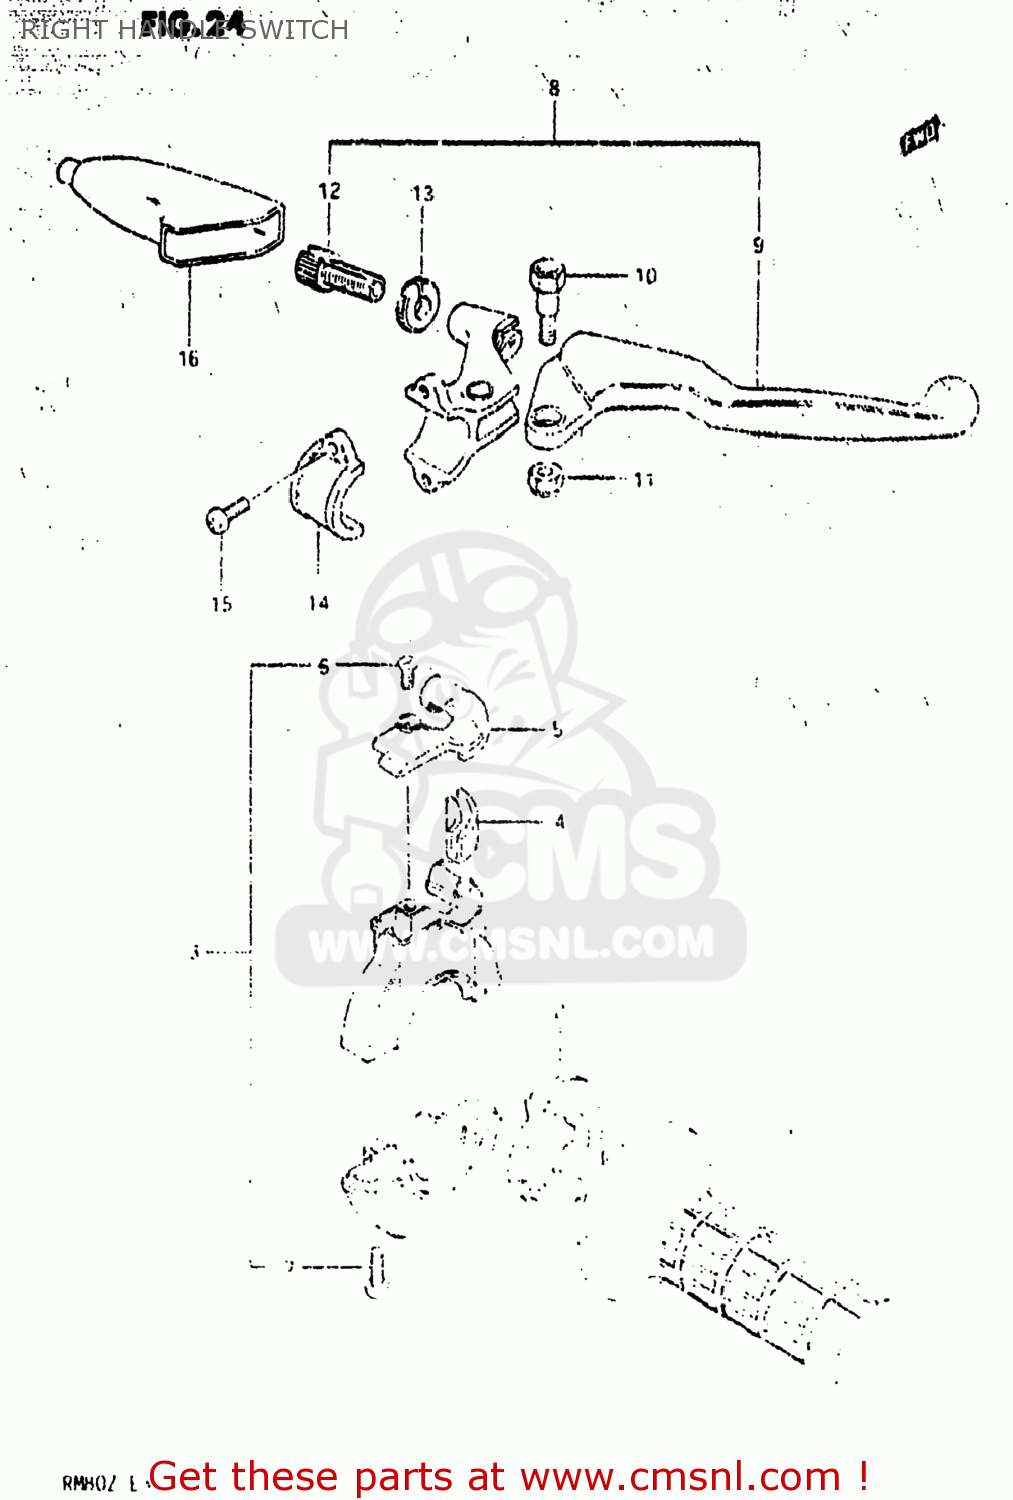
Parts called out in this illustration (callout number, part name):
1	GRIP,THROTTLE
2	ROTOR,THROTTLE GRIP
3	CASE ASSEMBLY,THROTTLE
4	GUIDE PIECE,THROTTLE
5	COVER,THROTTLE CASE
6	SCREW
7	SCREW
8	LEVER ASSY,BRAKE
9	LEVER,BRAKE
10	BOLT,LEVER
11	NUT 6MM
12	ADJUSTER,CABLE
13	NUT,CABLE ADJUSTER
14	BRACKET,CLUTCH LEVER HOLDER
15	SCREW
16	COVER,CLUTCH LEVER
